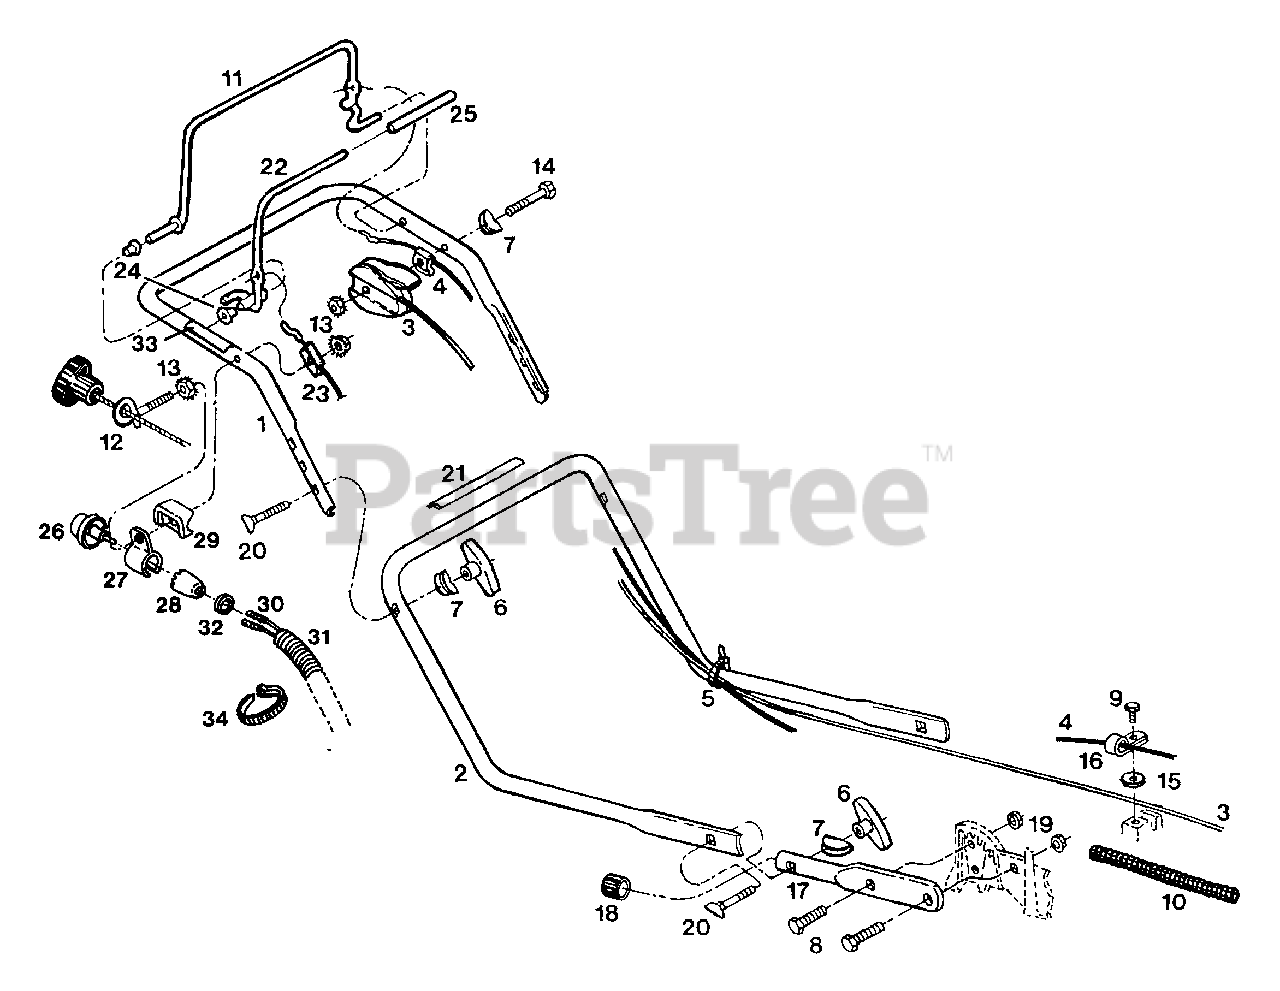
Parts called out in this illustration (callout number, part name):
1	Handle - Upper
2	Handle - lower
3	Control - throttle w/cable
4	Cable - engine/blade control
5	Cable Tie
6	Wing Nut - plastic
7	Washer - 5/16 curved
8	Bolt - hex 5/16-18 x 1
9	Screw - 1/4-20 x 5/8 hex tap
10	Cover - cable
11	Bail - engine/blade control
12	Eyebolt - rope guide
13	Nut - hex 1/4-20 keps
14	Bolt - hex 1/4-20 x 2 1/2
15	Washer - flat 1/4
16	Clamp - engine control cable
17	Stub - handle mounting
18	Plug - stub end
19	Nut - hex 5/16-18 finge lock
20	Bolt - handle, curved head
21	Decal - Starting Instructions
22	Bail - ground drive control
23	Cable - drive control
24	Bushing - control bail
25	Sleeve - control bail
26	Switch - push button
27	Mount - switch
28	Housing - switch
29	Spacer - mounting
30	Harness - wiring
31	Cover - harness
32	Clip - harness cover
33	Decal - Press to Start
34	Tie - cable
